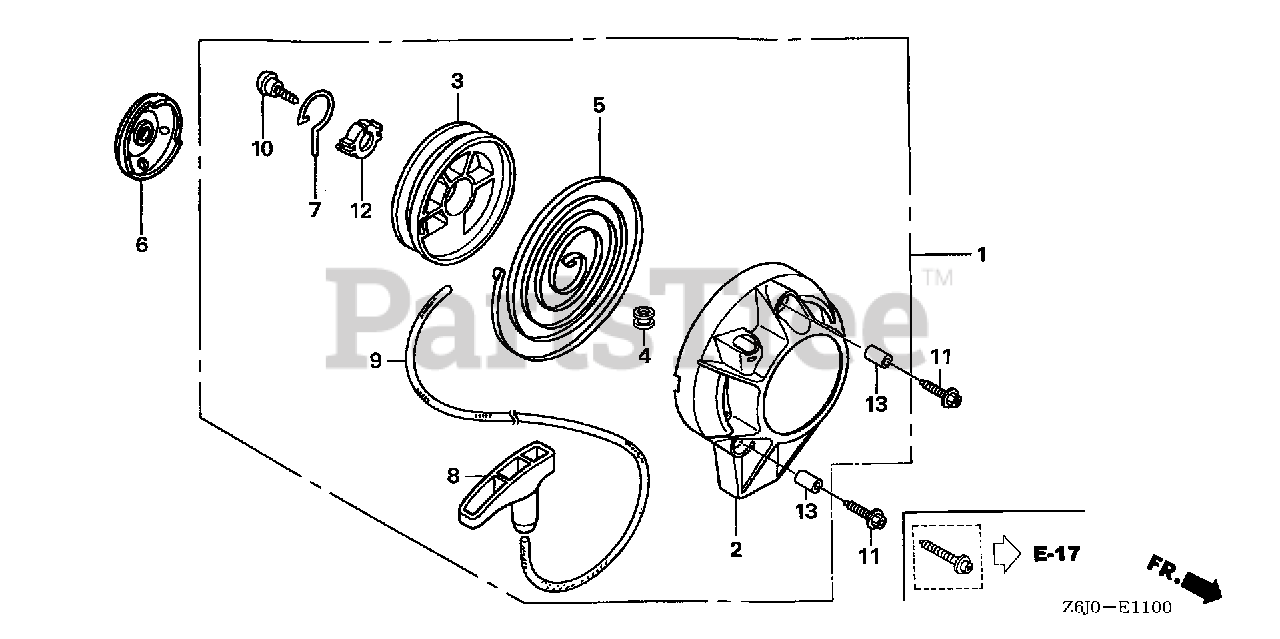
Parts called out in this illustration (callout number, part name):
1	TANK, FUEL
1	STARTER ASSY., RECOIL (FOR U.S.A.)
1	STARTER ASSY., RECOIL
2	CASE, RECOIL STARTER
3	REEL, RECOIL STARTER
4	GUIDE, ROPE
5	SPRING, RECOIL STARTER
6	PULLEY, RECOIL STARTER
8	KNOB, RECOIL STARTER
9	ROPE, RECOIL STARTER
10	SCREW, SETTING
11	BOLT, SOCKET (5X16)
13	COLLAR A, HEAD COVER
